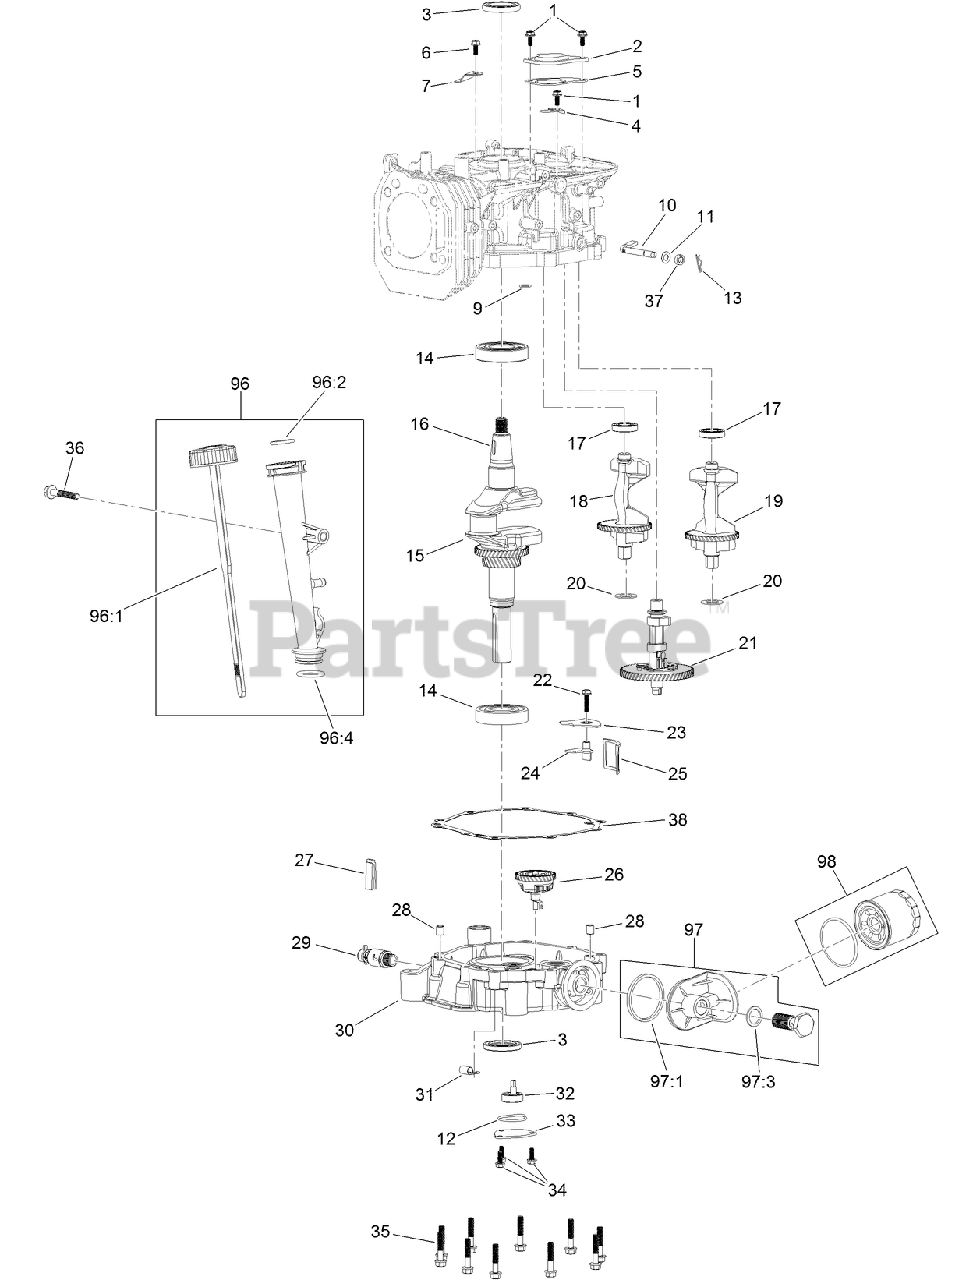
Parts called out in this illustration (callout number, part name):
1	SCREW-HHF
2	PLATE-BREATHER
3	SEAL-OIL
4	VALVE-REED
5	GASKET-BREATHER
6	SCREW-HHF
7	RETAINER
9	O-RING
10	SHAFT-GOVERNOR
11	WASHER-PLAIN
12	SEAL-PUMP, OIL
13	PIN-HAIR
14	BEARING-BALL
15	CRANKSHAFT
16	KEY-WOODRUFF
17	BEARING-BALL
18	SHAFT-BALANCE, R
19	SHAFT-BALANCE, L
20	WASHER
21	CAMSHAFT
22	SCREW-HHF
23	COVER-STRAINER, OIL
24	PLATE-BAFFLE, OIL
25	STRAINER-OIL
26	GEAR-GOVERNOR
27	DEFLECTOR-OIL, RUBBER
28	PIN-DOWEL
29	VALVE-DRAIN, OIL
30	COVER-CRANKCASE
31	CLAMP-HOSE
32	OIL PUMP ASM
33	COVER-PUMP, OIL
34	SCREW-HHF
35	SCREW-HHF
36	SCREW-HHF
37	SEAL-OIL
38	GASKET-CRANKCASE
96	DIPSTICK AND TUBE KIT
96:1	DIPSTICK ASM
96:2	O-RING
96:4	O-RING
97	OIL ADAPTOR KIT
97:1	SEAL-ADAPTOR, OIL
97:3	WASHER-FILTER, OIL
98	FILTER-OIL
